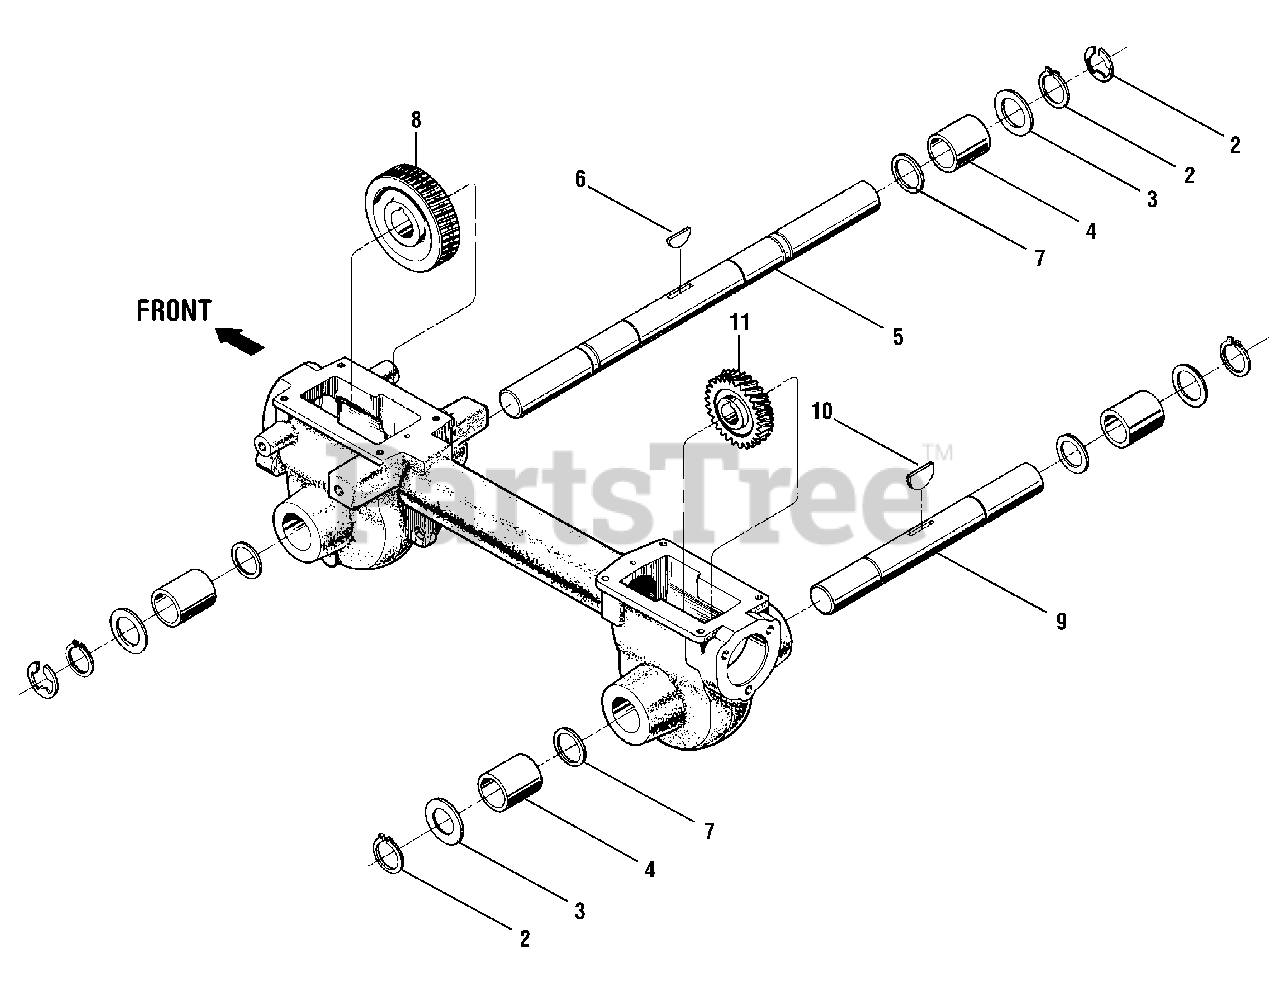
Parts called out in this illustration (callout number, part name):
2	Retainer, Snap Ring
3	Shim, 0.062" thick
3	Shim, 0.030" thick
3	Shim, 0.015" thick
3	Shim, 0.010" thick
3	Shim, 0.005" thick
4	Bronze Bushing
5	Wheel Shaft (for models 643C)
5	Wheel Shaft (for models 643B and 645A)
6	Key, Hi-Pro, 1/4 x 1
7	Spacer
8	Worm Gear, Wheel Shaft
9	Tiller Shaft
10	Woodruff Key
11	Worm Gear, Tiller Shaft
